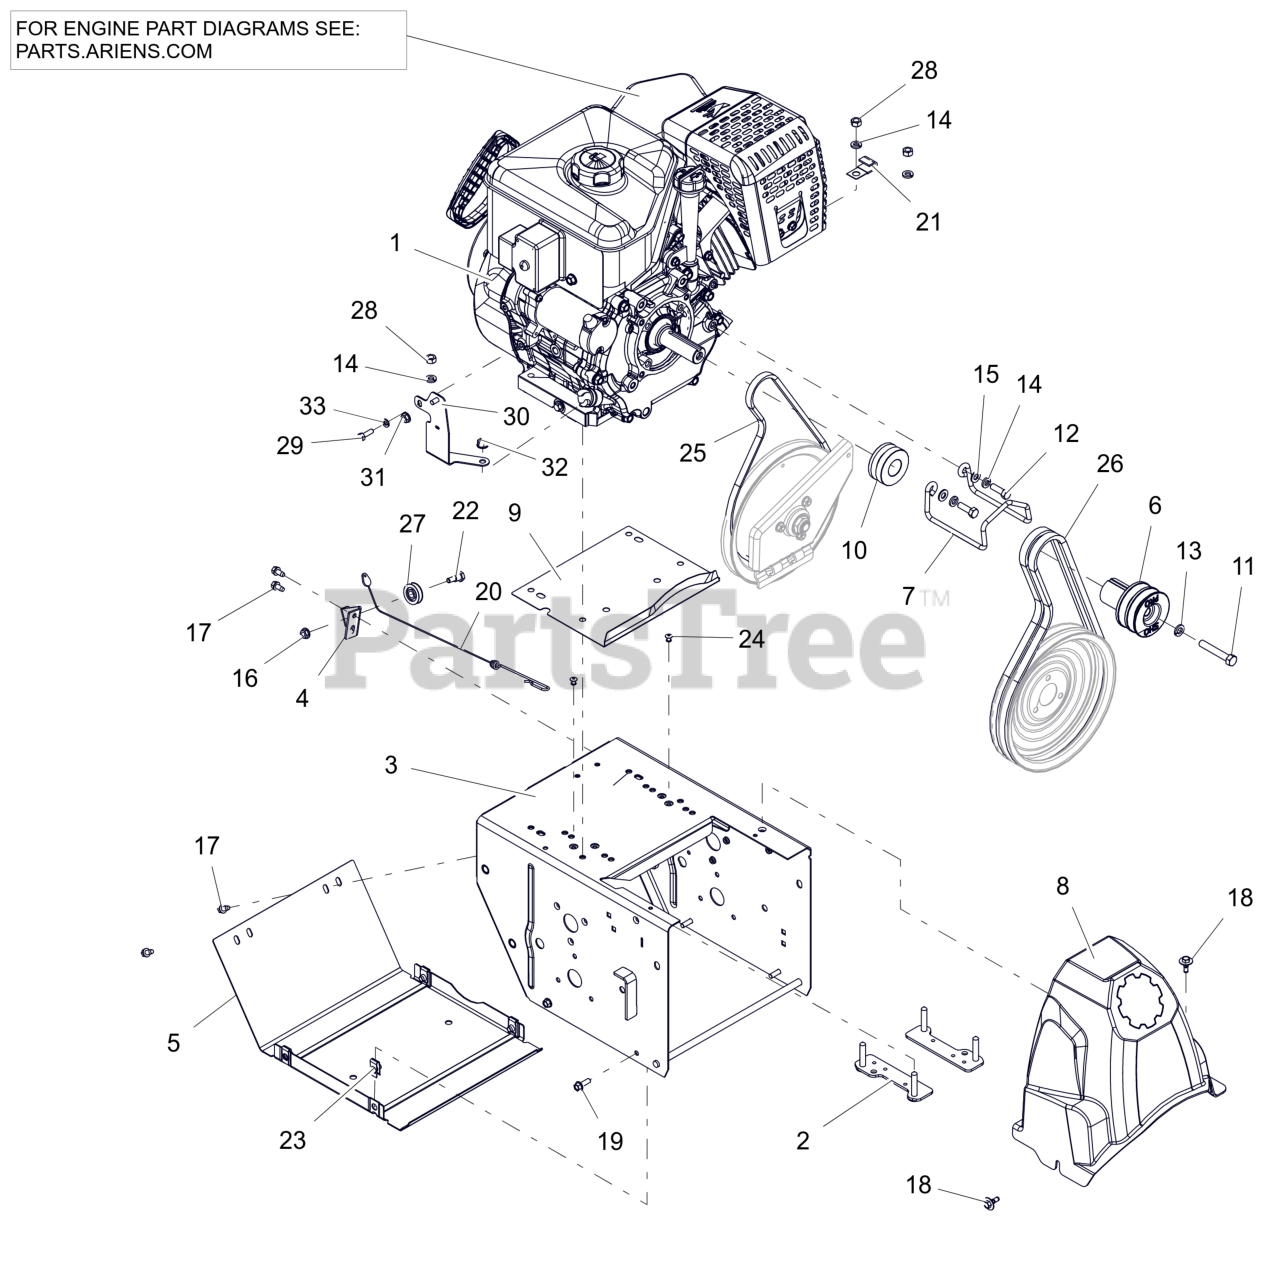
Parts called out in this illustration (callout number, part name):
1	ENGINE, EFI 369 GEN 3 240V/60W
2	STRAP, BOLT-LARGE
3	FRAME, MAIN - 14GA DELUXE (ORANGE)
4	BRKT, CABLE PULLEY
5	COVER, BOTTOM
6	SHEAVE,ATTACHMENT-SHO 2 GRV
7	FINGER, BELT
8	COVER, BELT
9	BAFFLE, WATER - LARGE BLOCK
10	SHEAVE, TRACTION (KEYLESS)
11	BLT, HEX .38-24X2.25 G5 ZCC
12	BLT, HEX 0.3125-24X1 G5 ZCC
13	WSHR,LK-REG .375X.094 ZCC
14	WSHR, LK-HVY .312X.097 ZCC
15	WSHR,FLT .344X.688X.065 ZCC
16	NUT-LK-TOP-FLG .250-20 GF ZCC
17	SCR-TAP .25-20X.50 HWH ZCC
18	SCR-TAP .25-20X.5 CAPTIVE
19	BLT, HWH .25-20X.75 G5 ZCC
20	CABLE, LOWER TRACTION,SS & PRO
21	J-CLAMP
22	BOLT, SHLDR -.375 X .375 X .25-20
23	NUT-RTNR .25-20X.56
24	RVT, POP .1875 ZCC
25	V-BELT, 3L-WRAPPED
26	V-BELT, HA-RAW EDGE (SET)
27	PULLEY, CABLE
28	NUT, HEX .312-18 ZCC
29	BLT,HEX M6-1X20 G8.8 ZC120
30	WLDMT- LG BLOCK FUSE MOUNT
31	NUT-LK-CTR-FLG .25-20 ZC120
32	NUT,LK-CTR-FLG .31-18 GF ZCC
33	WSHR,LK-REG .250X.062 ZCC
